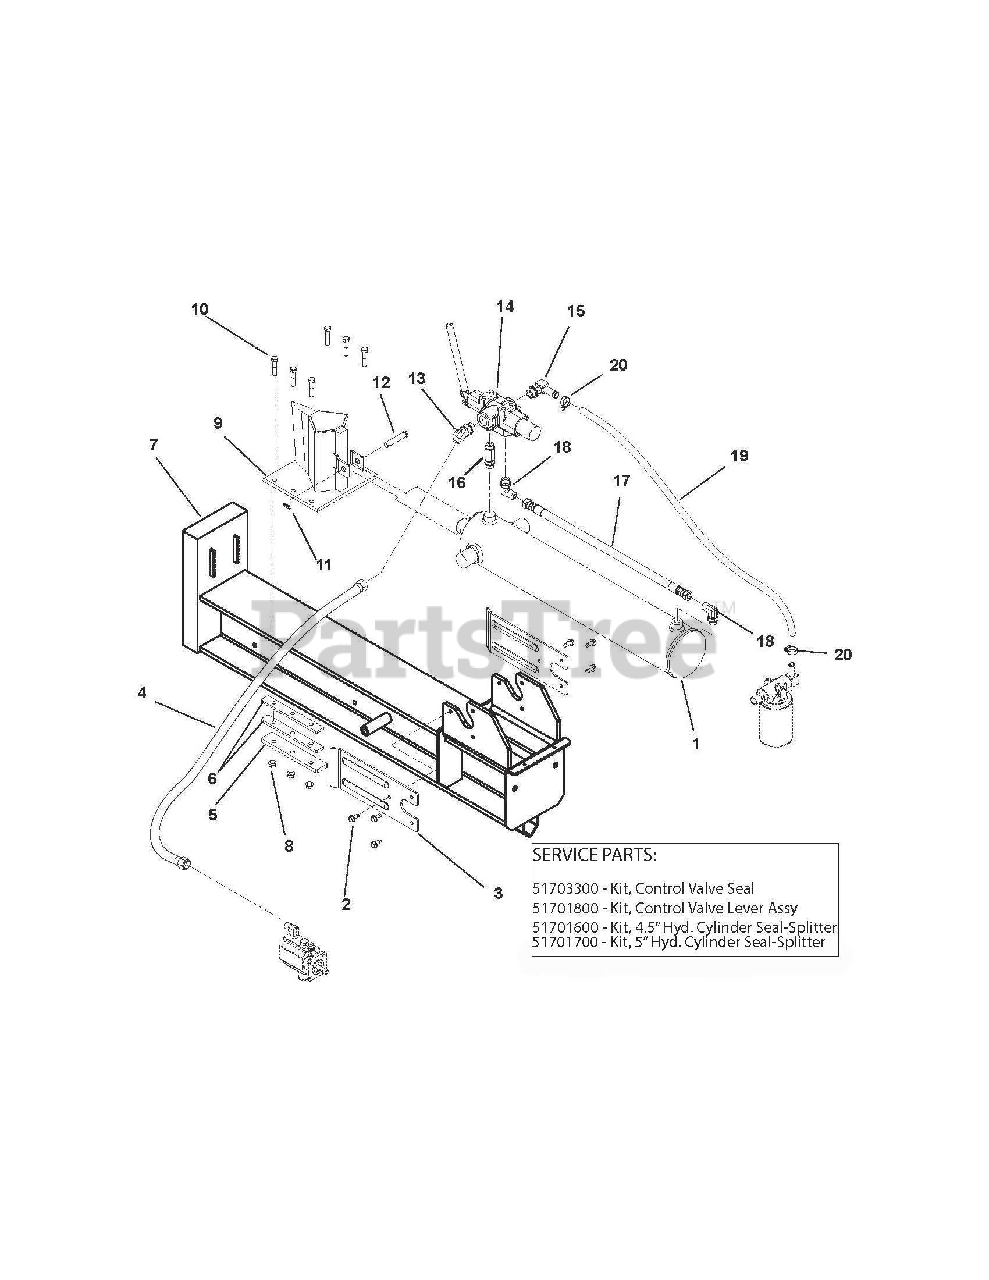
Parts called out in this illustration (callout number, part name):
1	CYLINDER,4.5 W/DECALS
1	KIT,4.5" HYD CYL SEAL-SPLITTER
1	CYLINDER, 5' W/DECALS
1	KIT, 5" HYD CYL SEAL-SPLITTER
2	@SCR-TAP .31-18X.75 HWH TR YWZ
3	PLATE,STRIPPER
4	HOSE, ASM - 46"
5	RETAINER,WEDGE
6	SPACER,WEDGE
7	WLDMT, SPLITTER BEAM
8	@NUT-LK-TOP-FLG .38-16 YWZC
9	WEDGE
10	@BLT-HEX .38-16X1.75 GR5 YWZC
11	CLIP, SPRING
12	PIN-CLEV .494X2.50 BRIGHT ZINC
13	FTG,HYD 6802-8-10
14	VALVE CONTROL-SPLITTER
14	KIT,CONTROL VALVE SEAL
14	KIT,CONTROL VALVE LEVER ASSY
15	FTG,HYD 4601-10-10
16	FTG,HYD 6403-NWO-8-8-L
17	HOSE, HYD - 22"
18	FTG,HYD 6801-8-8
19	HOSE,HYD RETURN 10LOLA X 53"
20	CLAMP,.88 DIA. HOSE
